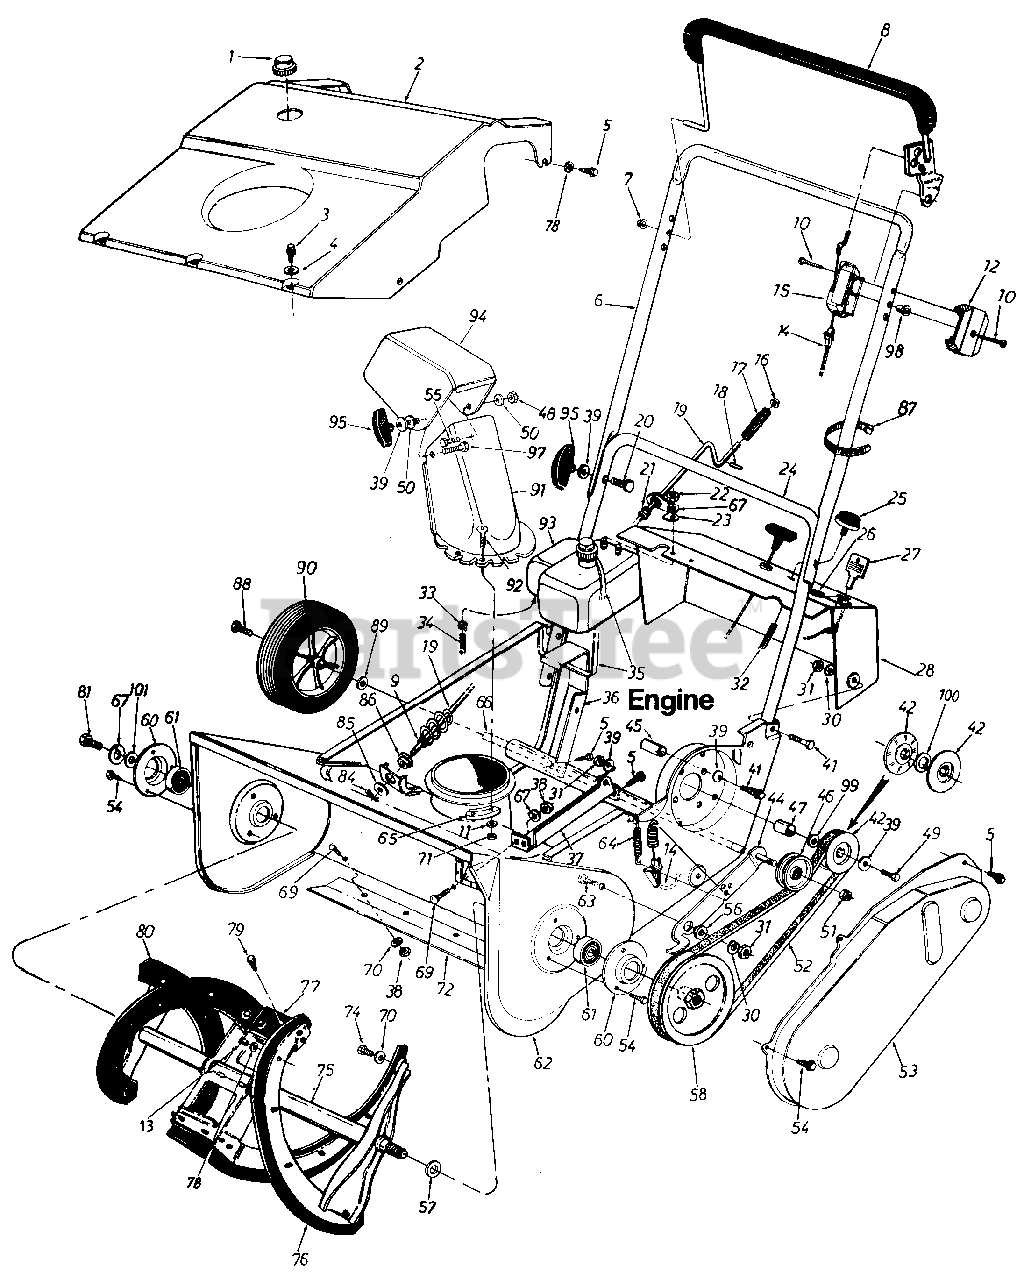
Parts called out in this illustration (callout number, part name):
1	Gas Tank Cap
2	21" Shroud
3	Hex B-Tap Scr. #10 x .38"
4	Spr.-Wash. .206" I.D. x .448"
5	Hex L-Wash. Hd. AB-Tap 0 0 1/4 x .62" Lg.
8	Control Handle Ass'y. L.H.
9	Fl-Wash. .385" I.D. x .62"
10	Truss Mach. Hi-B Tap Scr. #12 x 1.5" Lg.
11	Fl-Wash. .281" I.D. x .5" O.D.
12	Control Panel Half
13	Pop Rivet .188" Dia.
14	Clutch Cable 35" Lg.
15	Control Panel Half
16	Push Cap 3/8" Rod
17	Knob 3/8" Dia. Hole
18	Roll Pin 1/8" Dia. x .63" Lg.
19	Chute Crank Ass'y.
20	Curved Carriage Bolt 5/16-18 x 1.75" Lg.
21	Chute Crank Grommet
22	Hex Nut 1/4-20 Thd.
23	Upper Chute Crank Brkt.
24	Lower Handle
25	Primer
26	Plastic Plug
27	Plastic Key
31	Hex Nut 5/16-18 Thd.
32	Primer Hose 11" Lg.
33	Hose Clamp 1/2" Dia.
34	Gas Line 12" Lg.
35	Cable Tie 17.75" Lg.
36	Engine Support Brkt.
37	Engine Support
38	Hex Jam Nut 1/4-20 Thd.
39	Bell-Wash. .345" I.D. x .88"
41	Hex Bolt 5/16-18 x 1 5" Lg.
42	3/8" "V"-Pulley Half .625" I.D. x 6.0" O.D.
44	Idler Brake Brkt. Ass'y.
45	Spacer .325" I.D. x .625" O.D. x .875"
46	Fl-ldler w/Flanges 2.12" O.D.
47	Spacer .635" I.D. x .89" O.D. x .57"
48	Hex L-Nut 5/16-18 Thd.
49	Hex Bolt 5/16-24 x .75" Lg.
52	"V"-Belt
54	Hex B-Tap Scr. 1/4" x .38" Lg.
55	Carriage Bolt 5/1 6-1 8 x .75"
56	Shld. Spacer .50" Dia. x 27n
57	Fl-Wash. .510" I.D. x 1.0" O.D.
58	3/8" "V"-Pulley 1/2-20 L.H. x 6"
64	Extension Spring 1.12" Lg.
65	Chute Flange Keeper
66	Wheel Axle 1/2" O.D. x 20.6" Lg.
67	L-Wash. 1/4" I.D.
69	Carriage Bolt 1/4-20 x .50
70	Fl-Wash. .281" I.D. x .73"
71	Hex L-Nut 1/4-20 Thd.
72	Shave Plate
74	Hex Wash. B-Tap Scr. 1/4 x .62"
76	Rubber Spiral L.H.
77	Rubber Paddle
78	Fl-Wash. .218" I.D. x .62"
79	Hex Wash. B-Tap Scr. #10 x .62" Lg.
80	Rubber Spiral R.H.
81	Hex Wash. TT-Tap Cl-Scr. 1/4-20 x .751 Lg.
84	Cotter Pin 3132" Dia. x .75"
85	Fl-Wash. .406" I.D. x 1.25"
86	Hex Bushing .385" I.D.
87	Cable Tie
88	Hex Tap Scr. 3/8-24 x .88" Lg.
89	Fl-Wash. .510" I.D. x .75"
90	Wheel & Tire Ass'y. 7" x 1.5"
91	Lower Chute
92	Truss Mach. Scr. 1/4-20 x .75
93	Fuel Tank Two Qt.
94	Upper Chute
95	Knob Handle Ass'y.
97	Carriage Bolt 5/16-18 x 1"
98	Control Disc Pin
99	Fl-Wash. .635" I.D. x 1.04" O.D.
100	Fl-Wash. .635" I.D. x 1.0" O.D.
101	Fl-Wash. .25" I.D. x .93"
